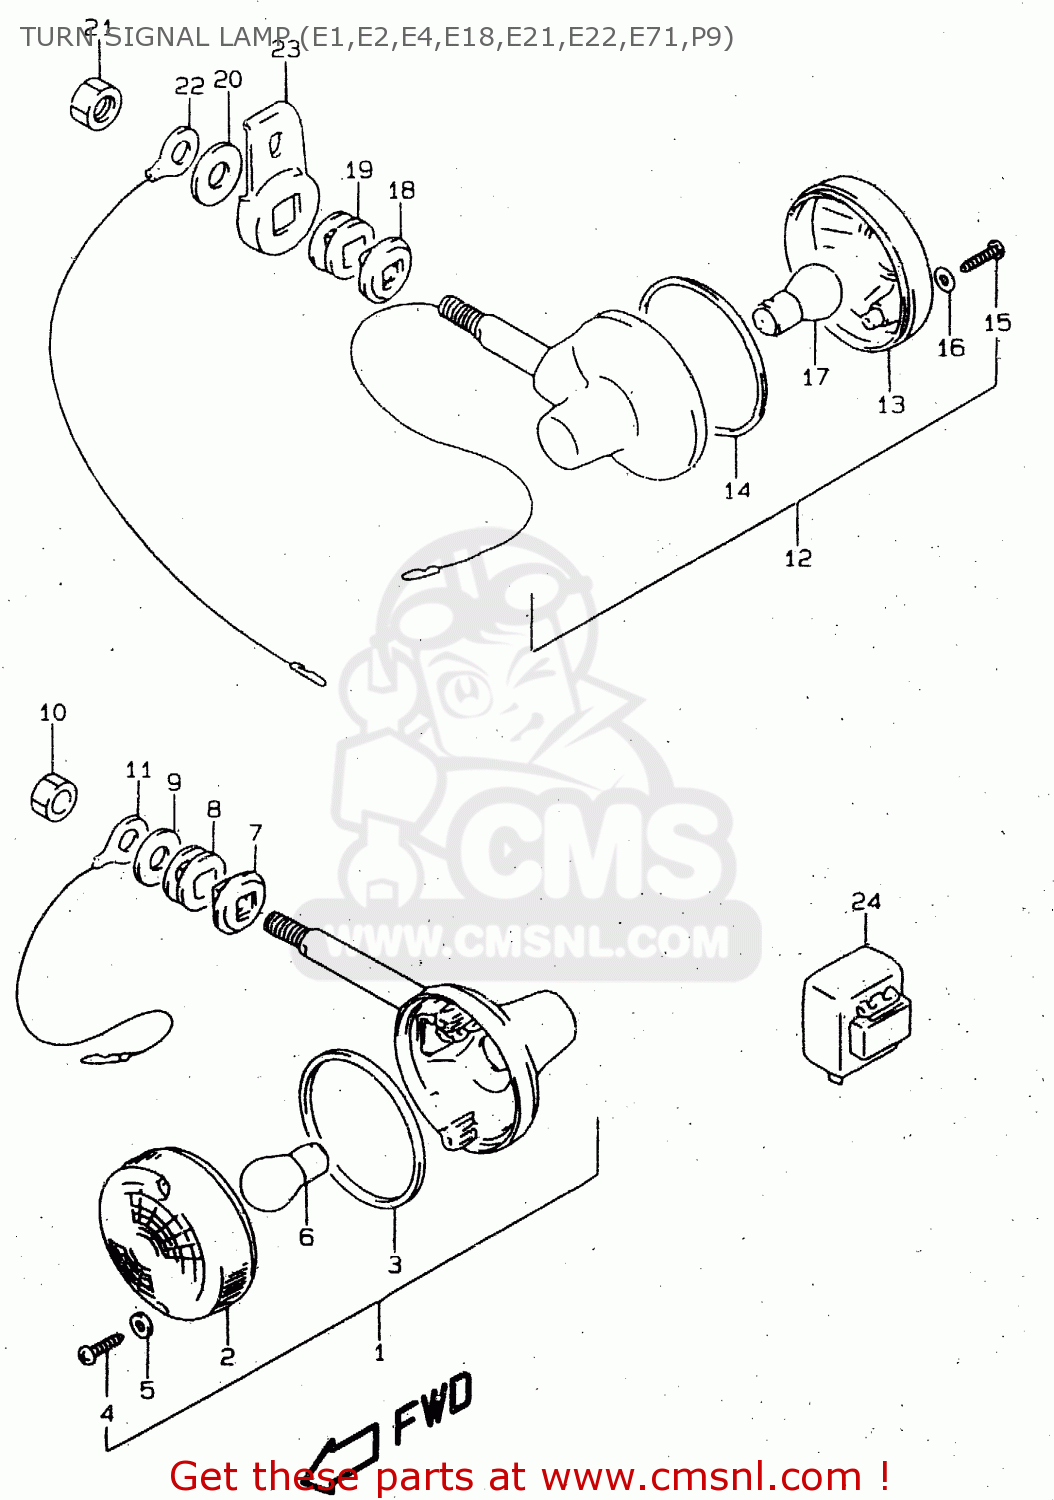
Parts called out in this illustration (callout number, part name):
1	LAMP ASSY,FR TURN SIGNAL
2	LENS
3	GASKET (NAS)
4	SCREW
5	GASKET (NAS)
6	BULB(12V21W)
7	SPACER
8	CUSHION
9	WASHER(10.5X30X2.3)
10	NUT
11	LEAD WIRE,EARTH
12	LAMP ASSY,RR TURNSIGNAL
13	LENS
14	GASKET (NAS)
15	SCREW
16	GASKET (NAS)
17	BULB(12V21W)
18	SPACER
19	CUSHION
20	WASHER(10.5X30X2.3)
21	NUT
22	LEAD WIRE,EARTH
23	BRACKET,RR TURNSIGNAL LAMP,R
24	RELAY ASSY,TUR
